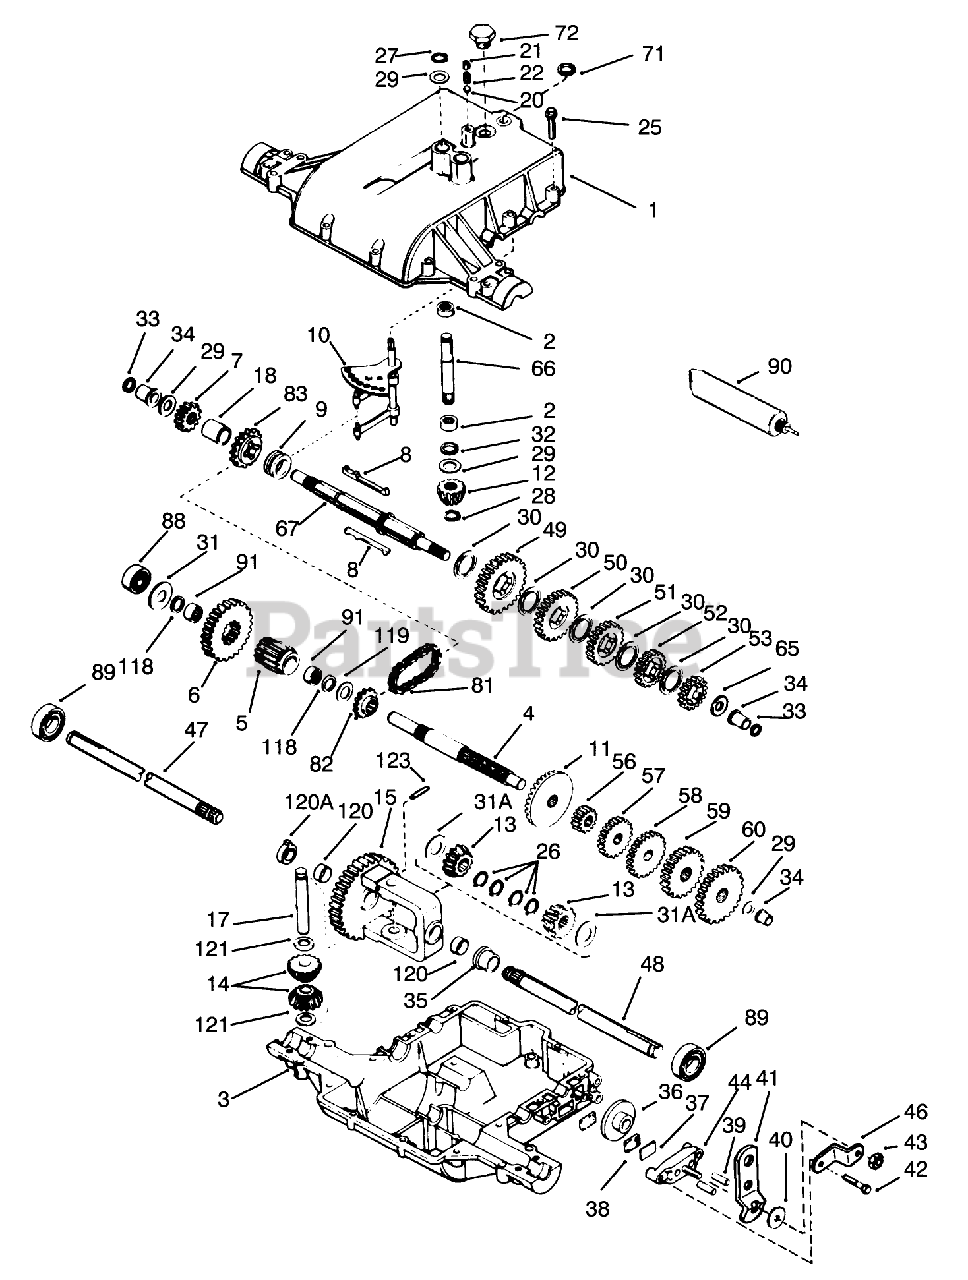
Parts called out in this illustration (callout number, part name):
1	Cover, Transaxle
2	Bearing, Needle
3	Case-transaxle
4	Shaft, Counter
5	Pinion-Output
6	Gear-Output
7	Gear-Spur 15 Teeth
8	Key
9	Collar-Shift
10	Rod Fork Assembly
11	Gear-Bevel, 42 teeth
12	Bevel Pinion-Input
13	Gear Bevel
14	Gear Pinion
15	Gear Assy., Differential (Incl. 2 of No. 120)
17	Drive Pin
18	Spacer
20	Ball-Steel
21	Screw-Set
22	Spring
25	Ring Set (.020 O S)
26	Retaining Ring (pkg of 2)
27	Ring-Snap
28	Ring-Retainer
29	Washer
30	Washer
31	Washer-Flat
31A	Washer
32	Seal, Square cut
33	Ring-Square Cut
34	Bushing-Flange
35	Bushing-Flanged
36	Disk
37	Brake Pad Plate
38	Brake Pad
39	Dowel Pin
40	Washer
41	Lever-Brake
42	Ring Set (.020 O S)
43	Locknut
44	Nozzle-Carburetor
46	Bracket
47	Axle (13-1/4" Long) (Incl. No. 26)
48	Axle (15-1 /8" Long) (Incl. No. 26)
49	Gear-Spur, 37 Teeth
50	Gear-Spur, 30 Teeth
51	Gear-Spur, 25 Teeth
52	Gear-Spur (22 teeth)
53	Gear-Spur 20 teeth
56	Gear-Spur, 12 Teeth
57	Gear-Spur, 20 Teeth
58	Gear-Spur, 25 Teeth
59	Gear-Spur (28 teeth)
60	Gear-Spur (30 teeth)
65	Washer
66	Shaft-Input
67	Shaft, Brake
71	Cut Seal-Square
72	Plug
81	Chain-Roller
82	Sprocket 10t
83	Sprocket (14 Teeth)
88	Bearing, Ball
89	Bearing-Ball
90	Grease 32 Oz
91	Bearing-Needle
118	Ring-Square Cut
119	Washer-Flat
120	Bushing
120A	Bushing
121	Thrust Washer
123	Pin-Roll
